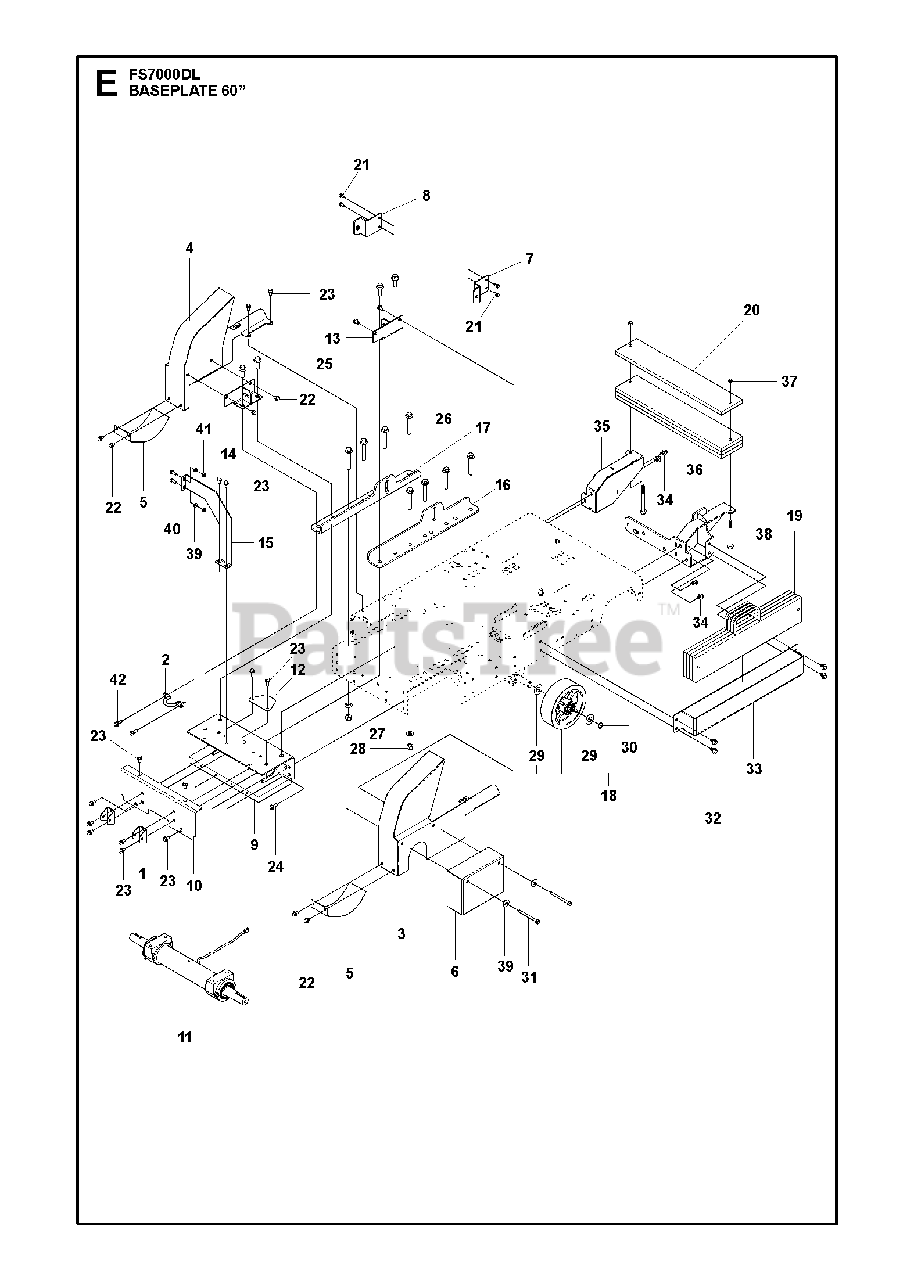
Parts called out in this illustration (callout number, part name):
30	CIRCLIP
39	WASHER
41	HEXAGON LOCKING NUT
